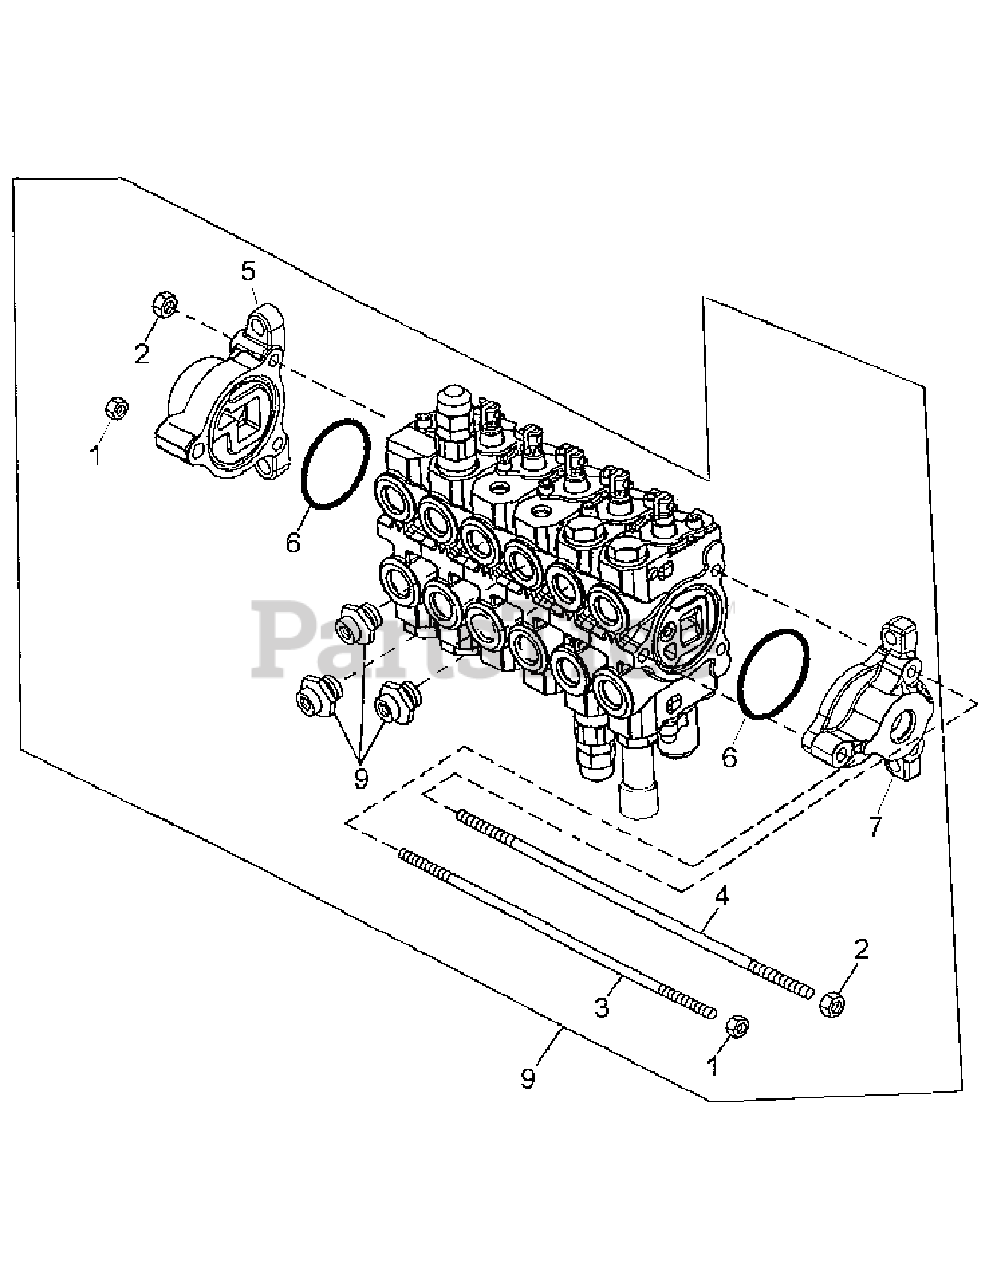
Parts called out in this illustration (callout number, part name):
1	NUT, 3/8
2	NUT, 5/16
3	TIE ROD
4	TIE ROD
5	OUTLET COVER
6	O-RING, SELECTION SEAL
7	INLET COVER WITH O-RING
8	RESTRICTOR ASSEMBLY-.064'' DIA
9	CONTROL VALVE ASSEMBLY
